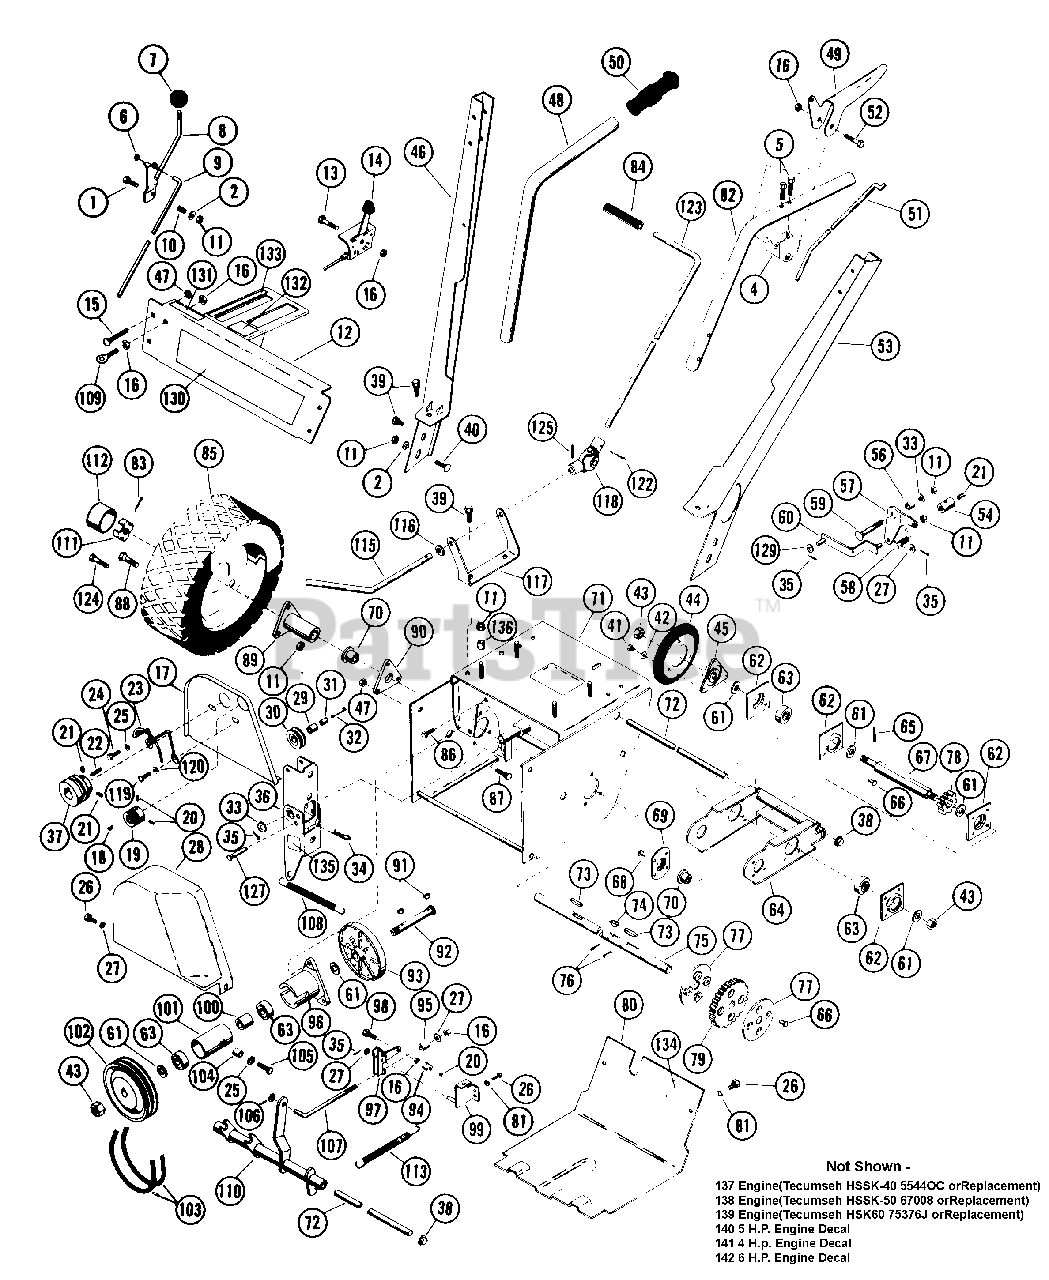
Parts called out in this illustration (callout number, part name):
1	BLT-HEX .31-18X1.50 PL GR2
2	WSHR-FL-STL.312X.734X.065PL
4	HANDLE PIVOT
5	SCR-TAP 12-14X1.50 CROVH PL BT
6	SPRINGGRIP FASTENER
7	SHIFT BALL
8	SHIFT HANDLE
9	SHIFT ROD
10	SG-COMP .105X.585X.75
11	NUT-LK .312-18 GR A PL
12	HANDLEBAR SERVICE ASSEMBLY
13	BLT-HEX .25-20X.75 PL GR2
14	THROTTLE CONTROL
15	BLT-RDHDSQNK .25-20X1.50 SHTPL
16	NUT-LK-CTR .250-20 PL
17	INNER BELT COVER
18	KEY-WDRF .125X.625X.250 SAE5
19	CAMSHAFT SHEAVE
20	SCR-SET .25-20X.25 SKHCUPNY OH
21	SCR-SET .32-18X.38 SKHCUPNL OH
22	KEY-SQ .188X1.0X.188 SAE 8630
23	BELT FINGER
24	BLT-HEX .31-24X.75 PL GR5
25	WSHR-LK .312X.097 PL HVY
26	BLT-HEX .25-20X.50 PL GR2
27	WSHR-FL-STL .250X.562X.049 PL
28	OUTER BELT COVER
29	BSHG-SLV .500X.625X.937
31	IDLER SHAFT
32	RVT-TBLR .187X1.218 OH ST PL
33	WSHR-FL-STL .38X.875X.083 PL
34	PIN-HAIR INT .08X.18X1.18
35	PIN-COTR .09X.75 PL
36	IDLER ARM ASSEMBLY
37	ENGINE SHEAVE
38	CAP, .50 ROD YWZC
39	BLT-SERHFWH .31-18X.50 PL
40	BLT-RDHDSQSHNK .31-18X.50 YZ
41	BLT-HEX .25-20X.38 PL GR2
42	WSHR-LK-EXT. 250 ID
43	NUT-LK-CTR .50-20 PL
44	FRICTION DISC
45	FRICTION DISC HUB
46	R H LOWER HANDLE BAR
47	NUT-LK-FLG .250-20 PL
48	R H UPPER HANDLEBAR
49	CLUTCH HANDLE
50	GRIP
51	CLUTCH ROD
52	BLT-HEX .25-20X1.75 PL GR2
53	L H LOWER HANDLE BAR
54	ROD ADAPTER
56	BSHG-SLV .334 X .502 X 1.437
57	SHIFT LEVER
58	BLT-HEX .31-18X.63 PL GR 2
59	BLT-RDHDSQNK .31-18X2.0 SHT PL
60	SHIFT LINK
61	WSHR-FL-STL .505X1.000X.062
62	BEARING RETAINER
63	BRG-BALL .500X1.38X.437
64	CARRIER
65	PIN-ROLL .188X1.00
66	RVT-POP .187X.402 DOME ST
67	HEX SHAFT
68	RVT-POP.125 X .294 DOME
69	BEARING RETAINER
70	BSHG-FLG .750X1.000X.625X1.250
71	TRACTOR FRAME
73	KEY-FTHR .188X1.25X.187 SAE
74	KEY-WDRF .25X.750X.313 SAE91
75	AXLE SHAFT
76	PIN-ROLL .125X1.00
77	RETAINER PLATE
79	SPUR GEAR, FELLOWS 35T .750 ID
81	WSHR-LK .250X.077 HVY PL
82	L H UPPER HANDLEBAR
83	PIN-COTR .12 X 1.25 PL
85	WHL 10.25 IN O.D.
85	TIRE & WHEEL ASSEMBLY
85	TIRE 4.10/3.50-4
85	TUBE
85	T/WHL ASSY 4.80 X 8 AGRI LUG
85	WHL
85	BLT-HEX .38-16X.63 PL GR2
85	WSHR-LK .375X.094 MED PL
85	NUT-HEX .375-16
87	SCR-SLTR-SERNK .25-20X.62 PL
88	BLT-WHL .50-20X.75 GR5 PL
89	SCREW, SAUCER HEAD
89	WHEEL HUB
90	SUPPORT, BEARING
91	KEY-WDRF .125X.500X.203 SAE 3
92	SPINDLE
93	DRIVE DISK
94	ROD ADAPTER
96	DRIVE SPINDLE HOUSING
97	DEADMAN LEVER
98	BLT-HEX .25-20X.75 PL GR5
99	DEADMAN BRACKET
100	BEARING SPACER .75 X .5 X.88
101	SPINDLE HOUSING
102	DRIVE SHEAVE
103	V-BELT, SPECIAL-RAW EDGE (SET)
105	BLT-HEX .31-18X1.00 PL GR 2
106	RATCHET PLATE
107	ADJUSTMENT LINK
108	SG-TENS .063X.44X2.81 WLD 18
109	ROD HANGER EYEBOLT
111	SPINDLE CUP
112	HUB CAP
113	SG-TENS .125X.437X5.5 WLD 20
115	CLUTCH LEVER ROD
116	WSHR-FL-STL .382X.812X.023 PL
117	SUPPORT BRACKET
118	UNIVERSAL JOINT ASSEMBLY
119	SCR-MCH .31-24X.75 CRFL
120	WSHR-LK-EXT .313X.025
122	PIN-COTR .12X1.0 PL
123	CLUTCH ROD
124	BLT-HEX .31-18X.75 PL GR2
125	PIN-ROLL .125X.75
127	CLEVIS PIN
129	WSHR-FL-STL .250X.562X.125 PL
130	HANDLEBAR DECAL
131	IN-OUT LABEL
132	CAUTION DECAL
133	SHIFT DECAL
134	DISK ADJUSTMENT DECAL
135	IDLER ARM ADJUSTMENT DECAL
136	ENG BOLT SPCR
137	Engine(Tecumseh HSSK-40 5544OC orReplacement)
138	Engine(Tecumseh HSSK-50 67008 orReplacement)
139	Engine(Tecumseh HSK60 75376J orReplacement)
140	5 HP ENGINE DECAL
141	4 HP ENGINE DECAL
142	6HP ENGINE DECAL
